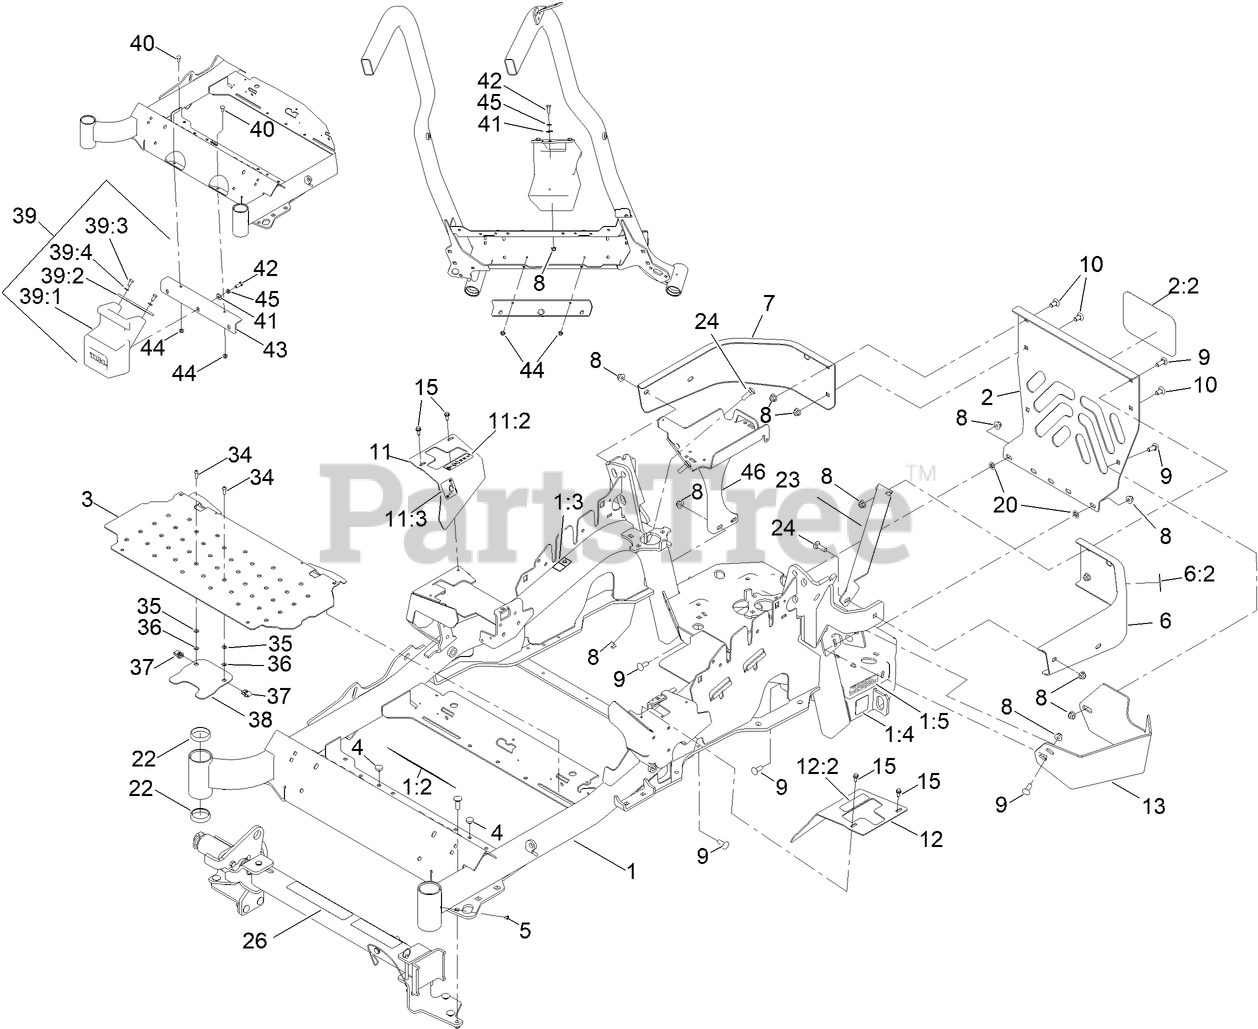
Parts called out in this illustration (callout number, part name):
1	MAINFRAME SERVICE ASM - 48/52
1:2	DECAL-DANGER
1:3	DECAL-WARNING
1:4	DECAL-HAZARD, PINCHED FINGER
1:5	DECAL-ARRESTOR, SPARK
2	REAR GUARD ASM
2:2	DECAL
3	FLOORPAN
4	BUMPER
6	LH BUMPER ASM
6:2	DECAL-WARNING
7	BUMPER-RH
8	NUT-HF, NI
9	SCREW-CARR
10	SCREW-CARR
11	RH MOTION CONTROL COVER ASM
11:2	DECAL-CONTROL, MOTION
11:3	DECAL-PARK BRAKE, CE
12	LH MOTION CONTROL COVER ASM
12:2	DECAL-CONTROL, MOTION
13	GUARD-MUFFLER
15	SCREW-HWH
20	NUT-PUSH
22	CUP-BEARING
24	BOLT-CARR
26	Z STAND ASM
34	SCREW-HSBH
35	WASHER-FLAT
36	PUSHNUT-RETAINER, BOLT
38	ADAPTER-CAPTIVE
39	WEIGHT ASM
39:1	WEIGHT-43 LB
39:2	TAB-SUPPORT, WEIGHT
39:3	SCREW-HH
39:4	WASHER-LOCK
40	SCREW-CARR
41	WASHER-FLAT
42	SCREW-HH
43	BRACKET-MOUNT, WEIGHT
44	NUT-HF, NI
45	WASHER-LOCK
46	BATTERY MOUNT ASM
